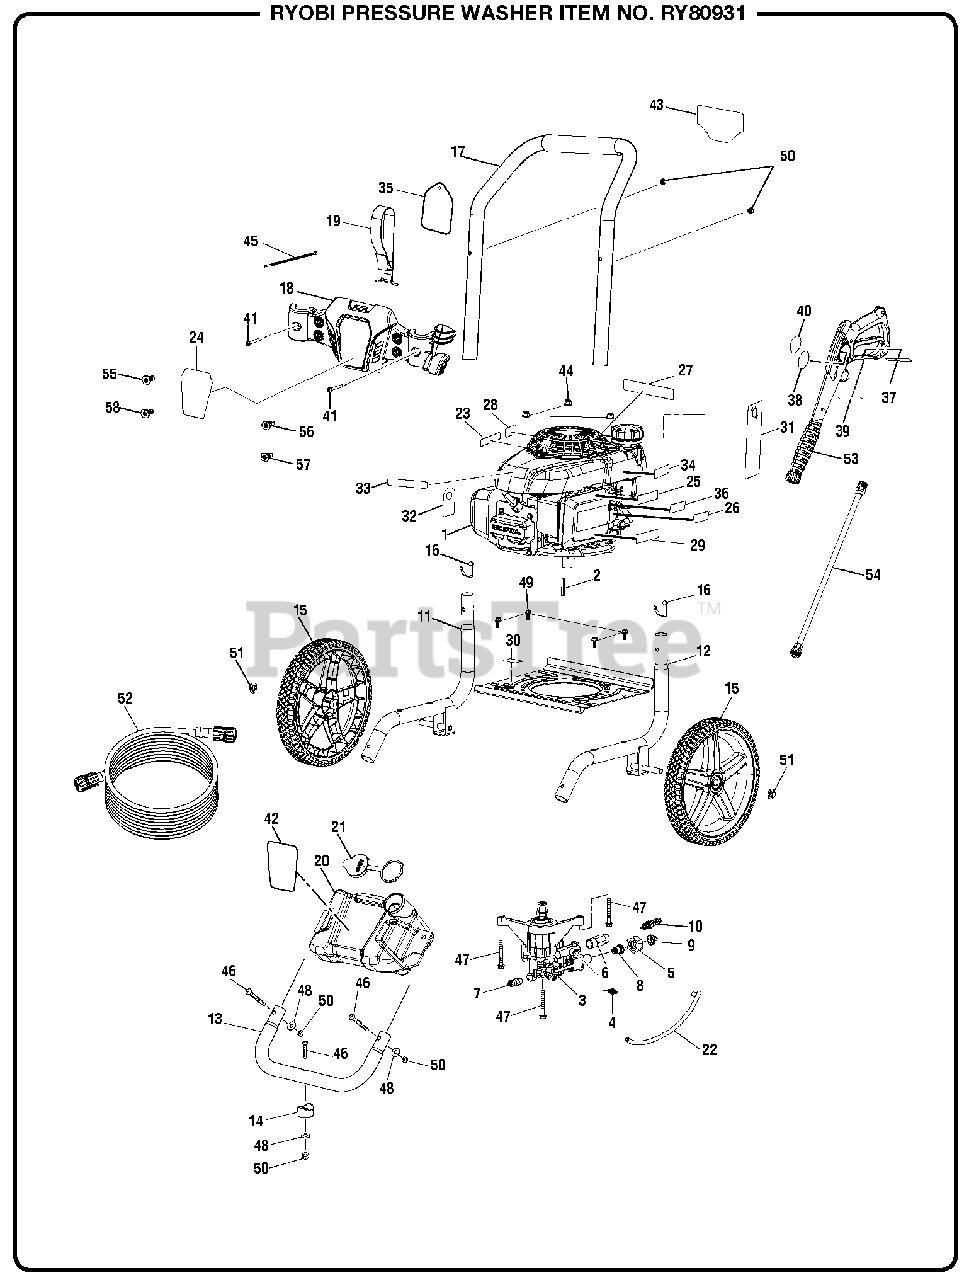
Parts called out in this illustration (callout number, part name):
1	Engine (Honda GCV 160, 160cc OHC Vertical)
2	Output Shaft Key (40 mm)
3	Pump
4	Detergent Suction Kit
6	Outlet Tube
7	Thermal Release Valve
9	Filter Screen (Pump Inlet)
10	Pump Unloader Valve
11	Main Frame Assembly
12	Main Frame Assembly
13	Front Frame
15	Wheel
16	Lock Button w/Spring Clip
17	Handle w/Foam
18	Hose and Nozzle Holder
19	Hose Holder Strap
20	Soap Tank
21	Soap Tank Cap
22	Chemical Siphon Tube
23	Hot Surface Label
24	Performance Label
25	Inquiries Label
26	Engine Control Label
27	Danger Label
28	Combustion Label
29	EMC Label
30	Engine Oil Fill Label
31	Danger Hangtag
32	Dipstick Hangtag
33	Honda Brand Label
34	No E85 Label
35	Nozzle Hangtag
36	Engine On/Off Label
37	Warning Label (Fr/Sp)
38	Label (Wand Warning)
39	Label (Wand Rating)
40	Wand Logo Label
41	Bolt (M6 x 42 mm, T-30 Torx Pan Hd.)
42	Soap Tank Label
43	Quick Start Panel
44	Flange Nut (M8)
45	Cable Tie
46	Screw (M6 x 48 mm, T30 Torx Hd.)
47	Bolt (M8 x 60 mm, Flange Hd.)
48	Washer (1/4 in.)
49	Bolt (M6 x 16 mm)
50	Lock Nut (M6)
51	Push Cap Nut (1/2 in.)
52	Hose (25 ft.)
53	Trigger Handle Assembly
54	Extension Wand
55	0deg Nozzle
56	25deg Nozzle
57	40deg Nozzle
58	Soap Nozzle
